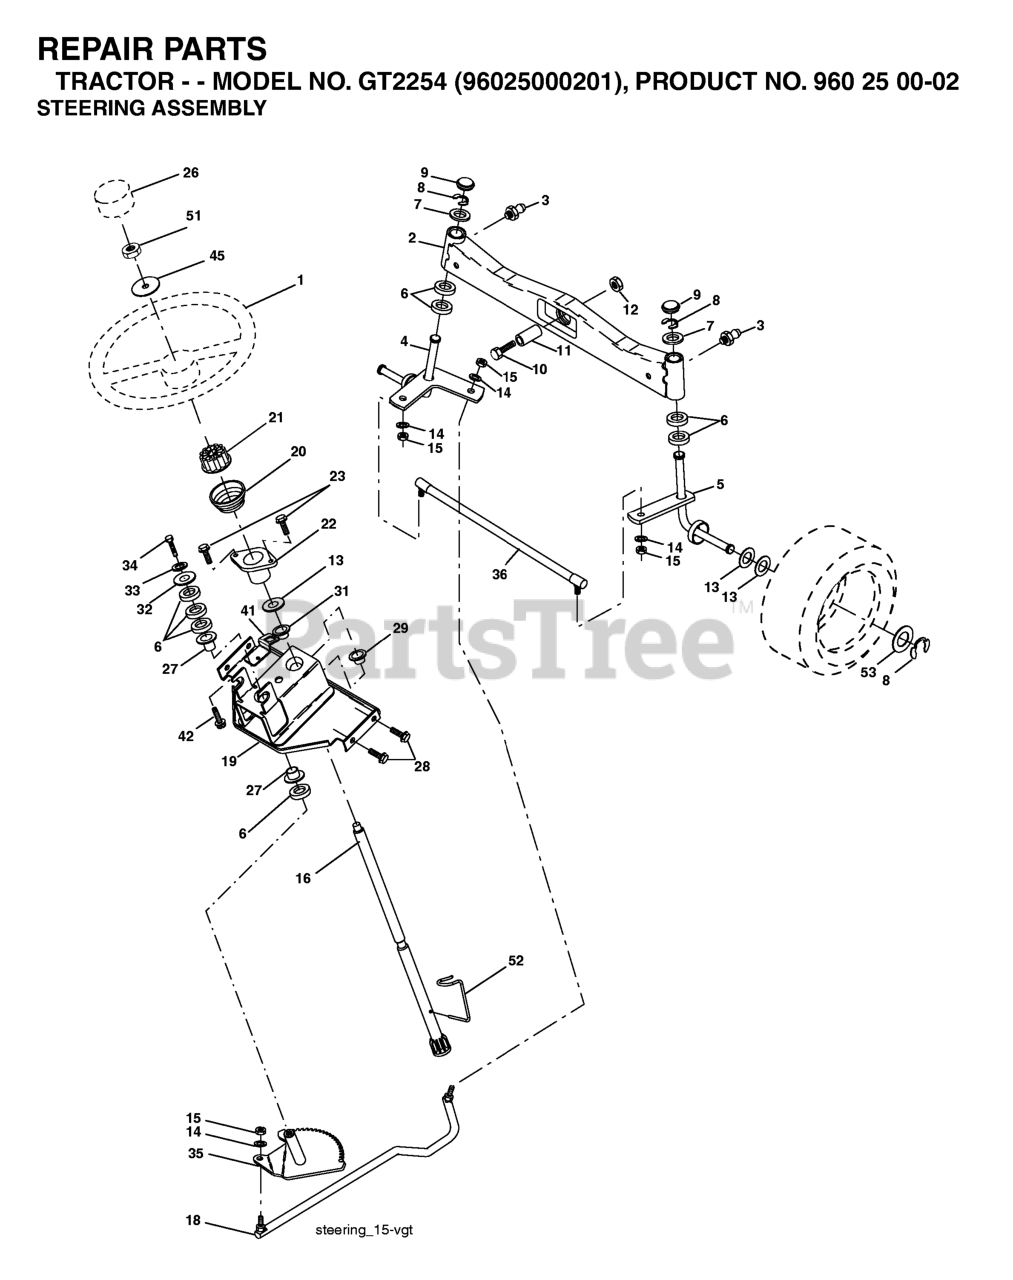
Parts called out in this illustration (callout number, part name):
1	WHEEL.STEERING.LEGEND2.GRY
2	AXLE.FRONT.CAST.MACHINE.W/ZERK
3	FITTING.GREASE.TAPERED
4	SPINDLE ASSY LH
5	SPINDLE ASM RH
6	THRUST WASHER
9	CAP.SPINDLE.BLACK
10	Bolt, Hex 5/8 -11 x 2 - 3/4 Gr. 5
11	TUBE, PIVOT AXLE
12	NUT-LOC,FLANGE LT
14	WASHER, LOCK 3/8
15	NUT CROWNLOCK 3/8-24
16	SHAFT ASM, STEERING
18	DRAGLINK.VGT.54"
19	SUPPORT ASM., STEERING VGT
20	BOOT, STEERING
21	ADAPTER, WHEEL STNG..
22	BUSHING, STRG. BLK
23	SCREW.TT.#10-32X.5.3/8.FLANGE
26	INSERT.CAP.STRG.WH.GRAY
27	BRNG T
28	SCREW, 3/8-16X3/4
29	BEARING-FLANGE GT
31	BUSHING.NYLINER.
33	WASHER.LOCK.HVY.HLCL.SPR.5/16
34	BOLT.FIN.HEX.5/16-18X3/4
35	GEAR.ASM.SECTOR.PITMAN
36	ROD.TIE.NON-ADJUSTABLE
41	BRACKET INTERLOCK
42	Screw 5/16-18 x 1/2 Hex, Self Tapping 5/16-18 x 1/2
44	EXTENSION STEERING PREMIUM
45	WASHER 9/16"ID, 2 3/8"OD
51	NUT.HEX.1/2-20
52	CLIP.STEERING
53	WASHER.HARDENED
